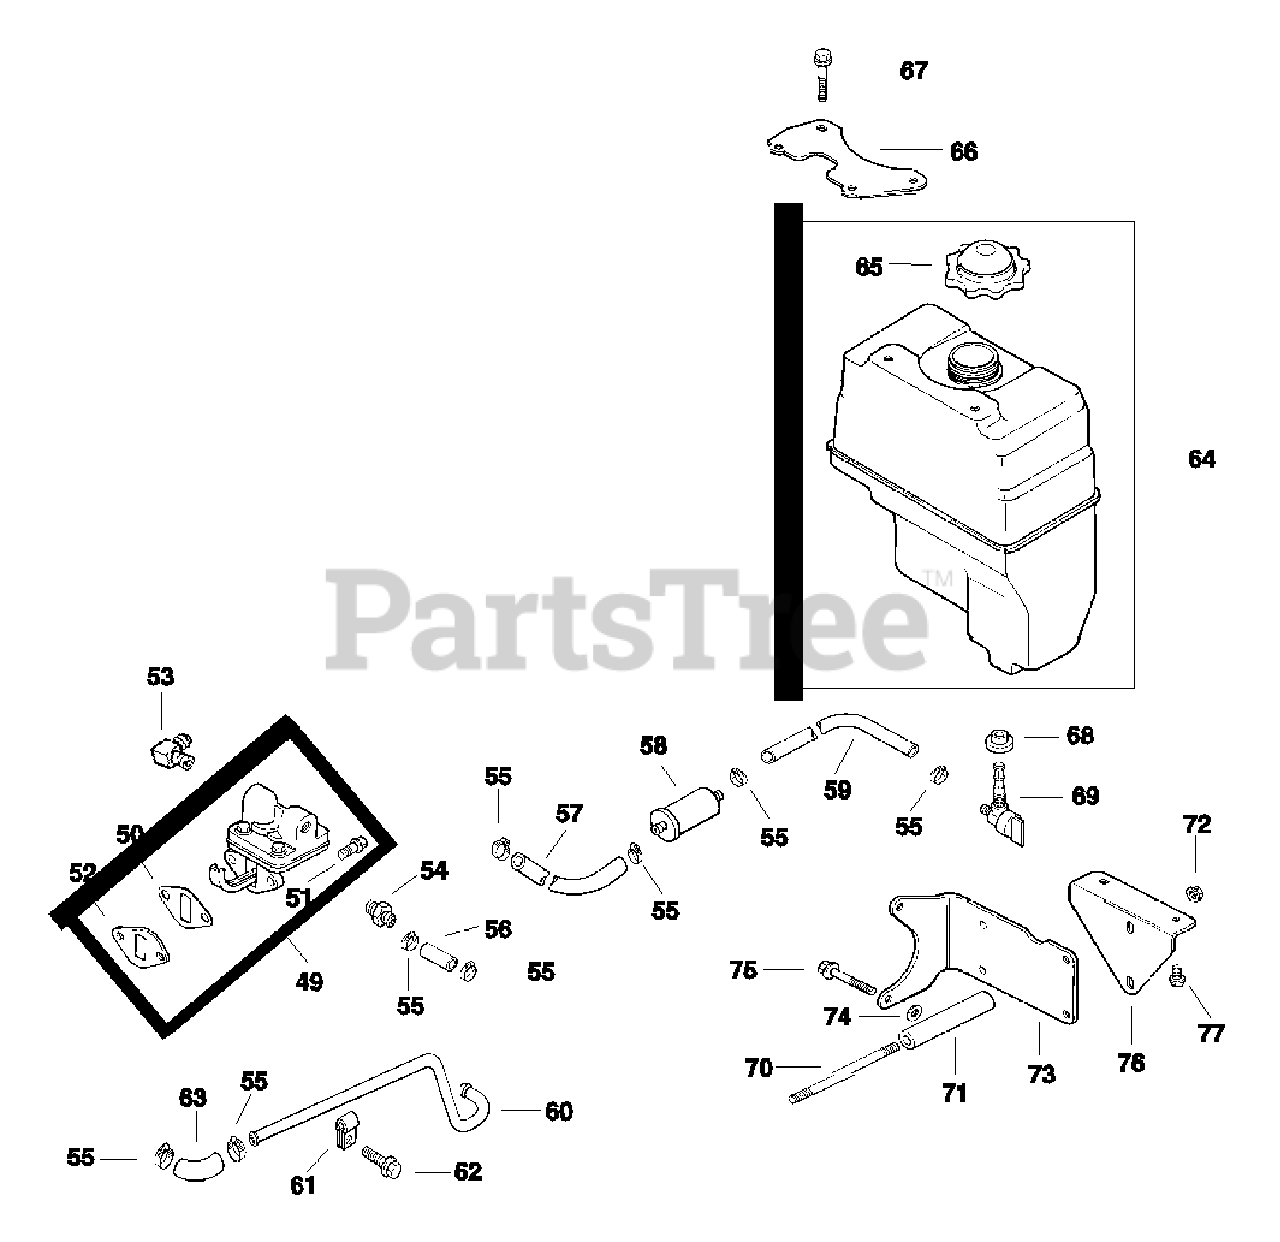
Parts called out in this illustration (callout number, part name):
49	KIT USE 12 559 02-S
51	SCREW - USE M-645020
52	SPACER, FUEL PUMP
53	CONNECTOR, 90 DEG. HOSE
54	CONNECTOR USE 25 326 03-S
55	CLAMP, HOSE 1/2" USE 25 237 14-S
56	LINE - DISCONTINUED
57	LINE - DISCONTINUED
59	LINE, FUEL 10"
60	LINE - USE 12 353 11
62	SCREW - USE M-545010
63	LINE, FUEL-FLEXIBLE - USE 25 111 36-S
64	KIT, FUEL TANK
66	BRACKET - USE 12 126 62
67	SCREW - USE M-645025
68	BUSHING, FUEL TANK
69	VALVE, FUEL SHUT-OFF
70	Stud, M8x1.25x128
71	SPACER - USE 12 112 12
72	Nut, hex. flange M8x1.25
73	BRACKET - USE 12 126 58
74	WASHER, FLAT 11/32"
75	SCREW, FLG M8X1.25X50
77	SCREW - USE M-650012
